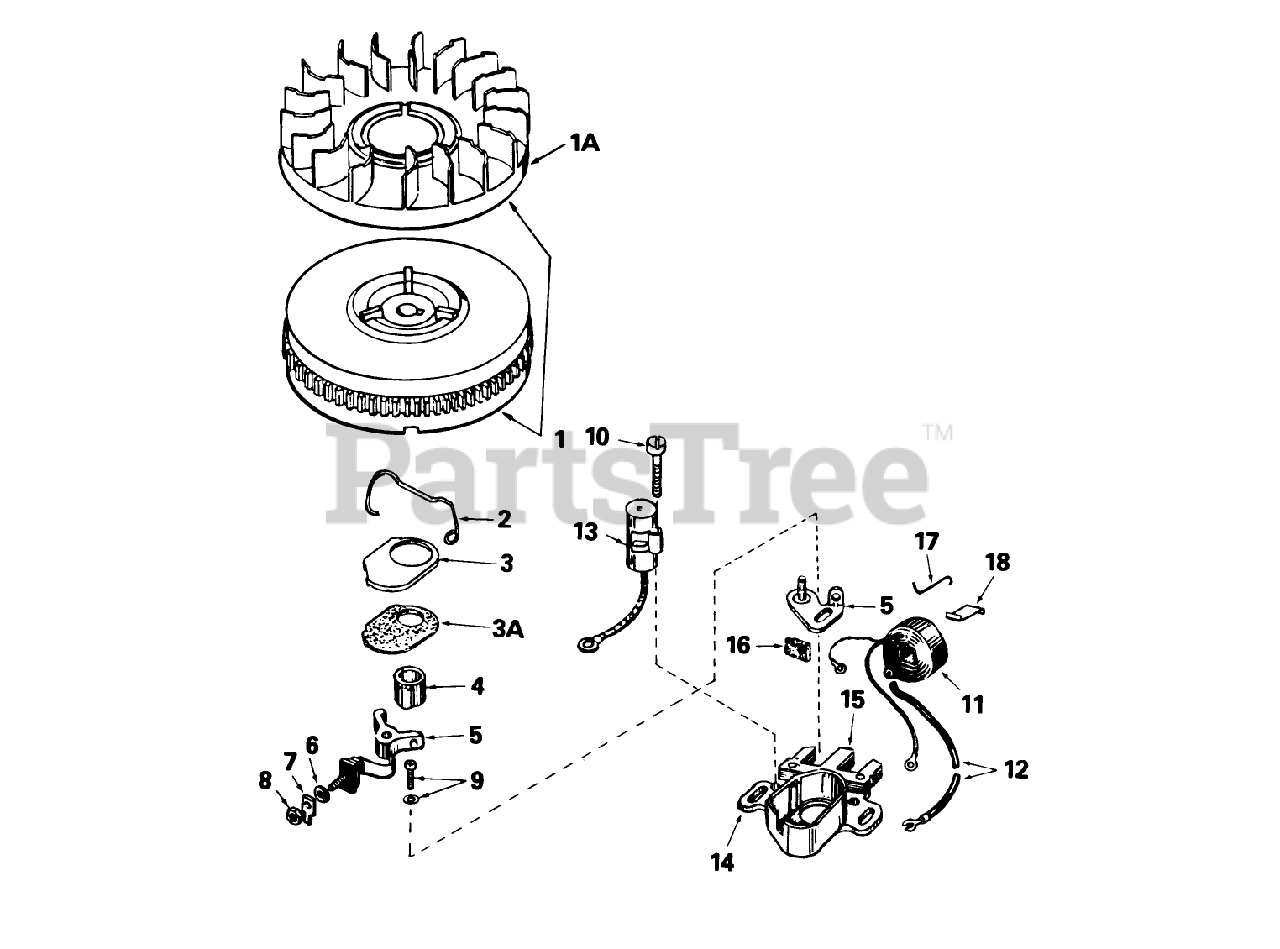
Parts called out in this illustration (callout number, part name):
1	Flywheel (Incl. Ref. #1A)
1A	Fan
2	Spring Breaker Box
3	Cover-Dust
3A	Gasket-Dust Cover
4	Cam-Breaker
5	Breaker Assy.
6	Washer
7	Terminal, Ground
8	DECAL
9	Breaker Screw
10	Condenser Screw
11	Coil Assy. (Incl. No. 12)
12	Wire, Lead
13	Condenser
14	Core Plate
15	Stator Assy. (Incl. Ref. #2 thru 11, 13, 14, 16, 17 19)
16	Felt,Cam Wiper
17	Clip, Coil
